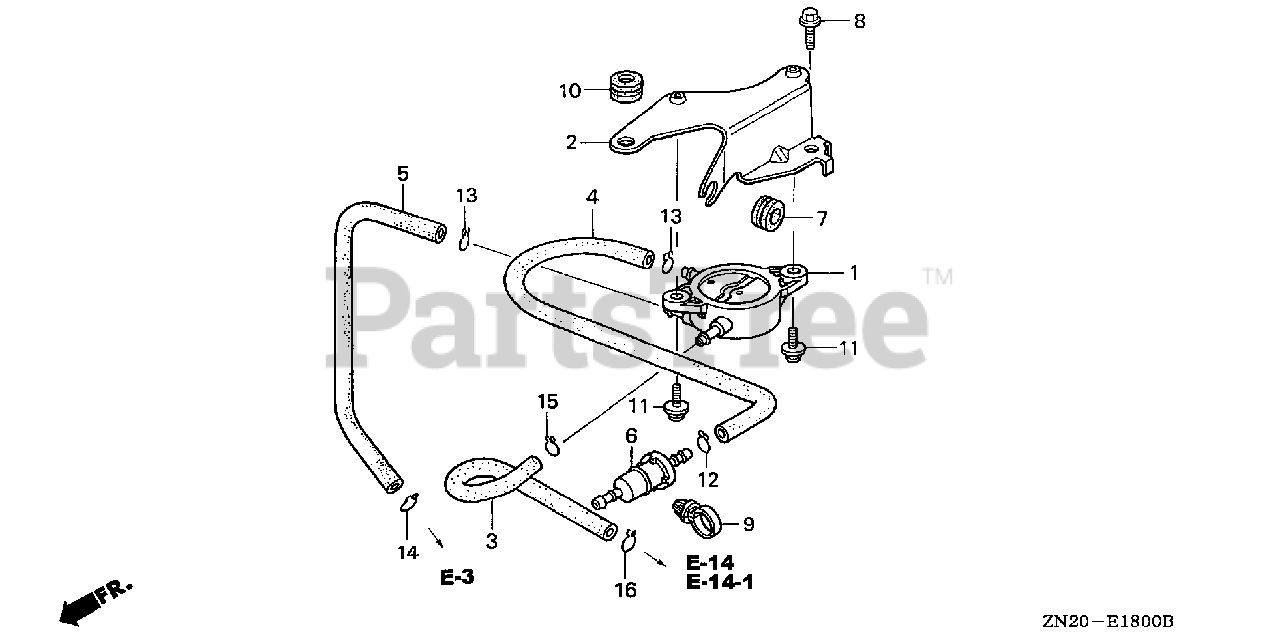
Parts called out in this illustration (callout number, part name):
1	PUMP ASSY., FUEL
2	STAY, FUEL PUMP
3	TUBE, FUEL
4	TUBE B, FUEL
5	TUBE, DIAPHRAGM
6	STRAINER, FUEL
7	GROMMET, RESERVE TANK
8	BOLT, FLANGE (6X14) (CT200)
9	CLIP, WIRE HARNESS
10	GROMMET, PUMP STAY
11	SCREW-WASHER (6X16)
12	CLIP, TUBE (B8)
13	CLIP, TUBE (B10)
14	CLIP, TUBE (C9)
15	CLIP, TUBE (C11)
16	CLIP, TUBE (B10)
